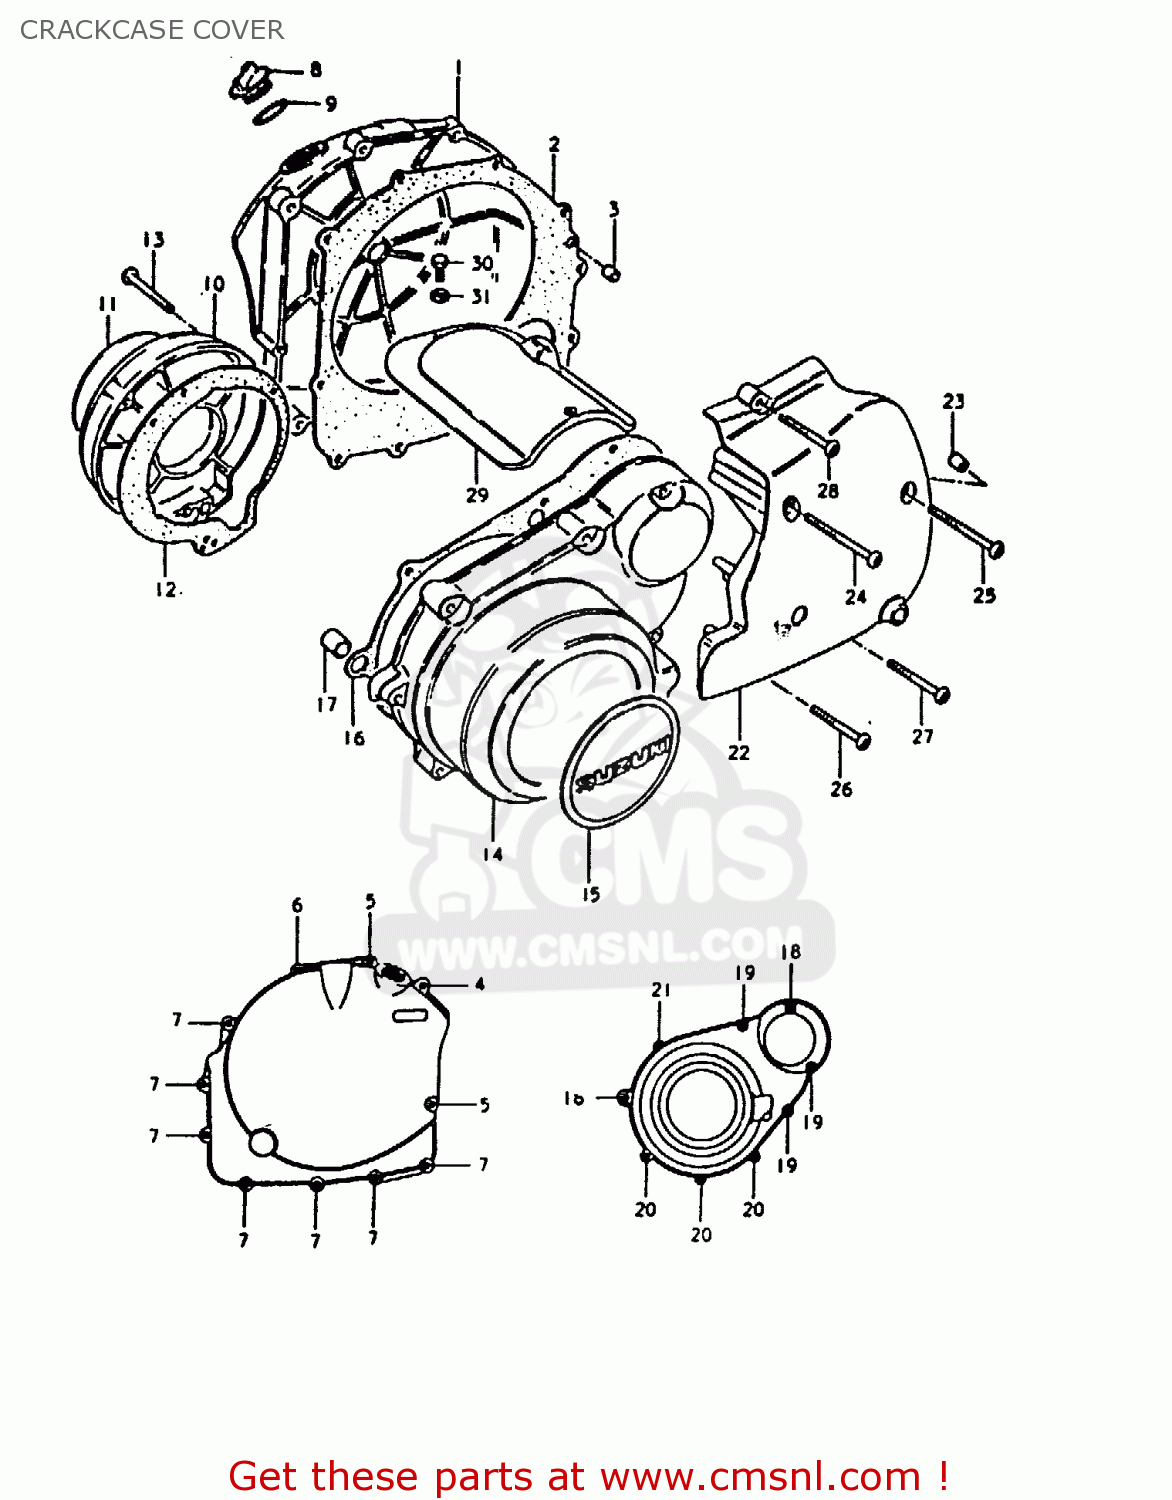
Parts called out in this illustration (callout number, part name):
1	COVER,CLUTCH
2	GASKET,CLUTCH COVER (MCA)
3	PIN
4	SCREW (6X35)
5	SCREW 6X30
6	SCREW
7	SCREW
8	CAP
9	O RING(D:2.2,ID:32)
10	COVER,CONTACT BREAKER
11	EMBLEM
12	GASKET,CONTACT BREAKER COVER (NAS)
13	SCREW
14	COVER
15	EMBLEM
16	GASKET,MAGNETO COVER (MCA)
17	PIN
18	SCREW (6X45)
19	SCREW
20	SCREW (6X35)
21	SCREW 6X30
22	COVER,ENGINE SPROCKET
23	PIN
24	SCREW(6X100)
25	SCREW 6X85
26	SCREW 6X70
27	SCREW
28	SCREW 6X30
29	COVER,STARTER MOTOR
30	BOLT
31	WASHER
